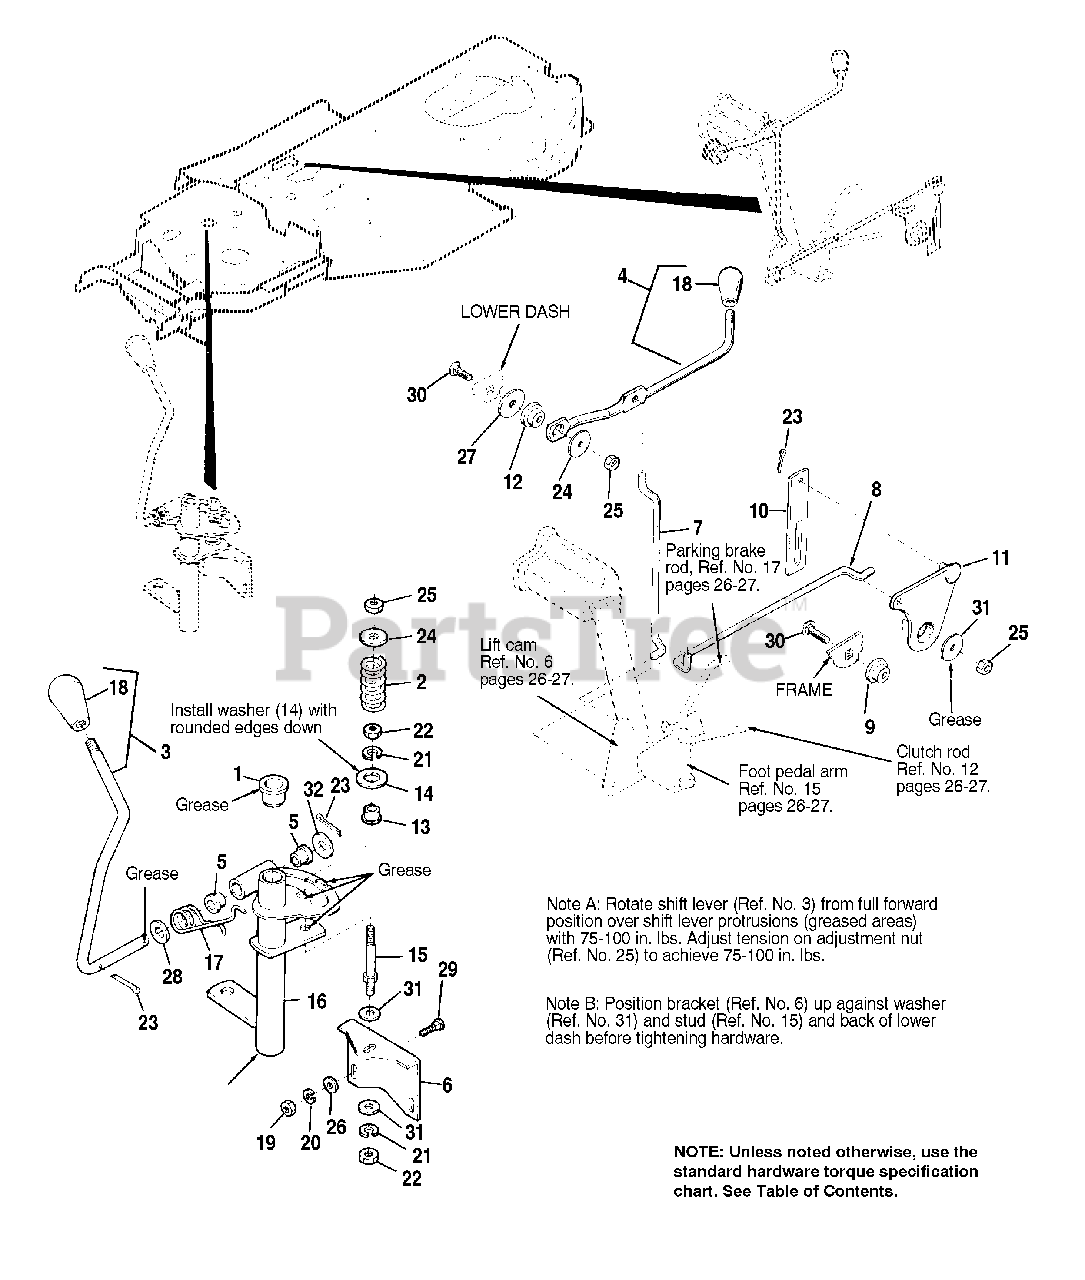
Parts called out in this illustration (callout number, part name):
1	BUSHING, Nylon, 3/4 Dia.
2	SPRING, Compression
3	LEVER, Shift
4	ROD, Lift Handle
5	BUSHING, Plastic, 1/2 Dia.
6	BRACKET, Tension
7	LINK, Lift Upper
9	SPACER
10	LINK, Lift, Upper Transport
11	CAM, Lift Assy.
12	SPACER
14	WASHER, 1/2
15	STUD, 5/16-18 x 3-1/4
16	SHIFT LEVER ASSY.
17	SPRING, Torsion
18	KNOB, Plastic
19	NUT, Hex, 1/4-20
20	LOCKWASHER, 1/4
21	LOCKWASHER, 5/16
22	NUT, Hex, 5/16-18
23	COTTER PIN
24	WASHER, Plain, 5/16
25	NUT, Hex, ESNA, Lock, 5/16-18
26	WASHER, Plain, 1/4
27	WASHER, Plain, 13/32 x 1-1/2 x 1/8
28	WASHER, Plain
29	CARRIAGE BOLT, 1/4-20 x 3/4
30	CARRIAGE BOLT, 5/16-18 x 1-1/2
31	WASHER, Plain, 21/64 x 1-1/4
32	WASHER, 1/2
